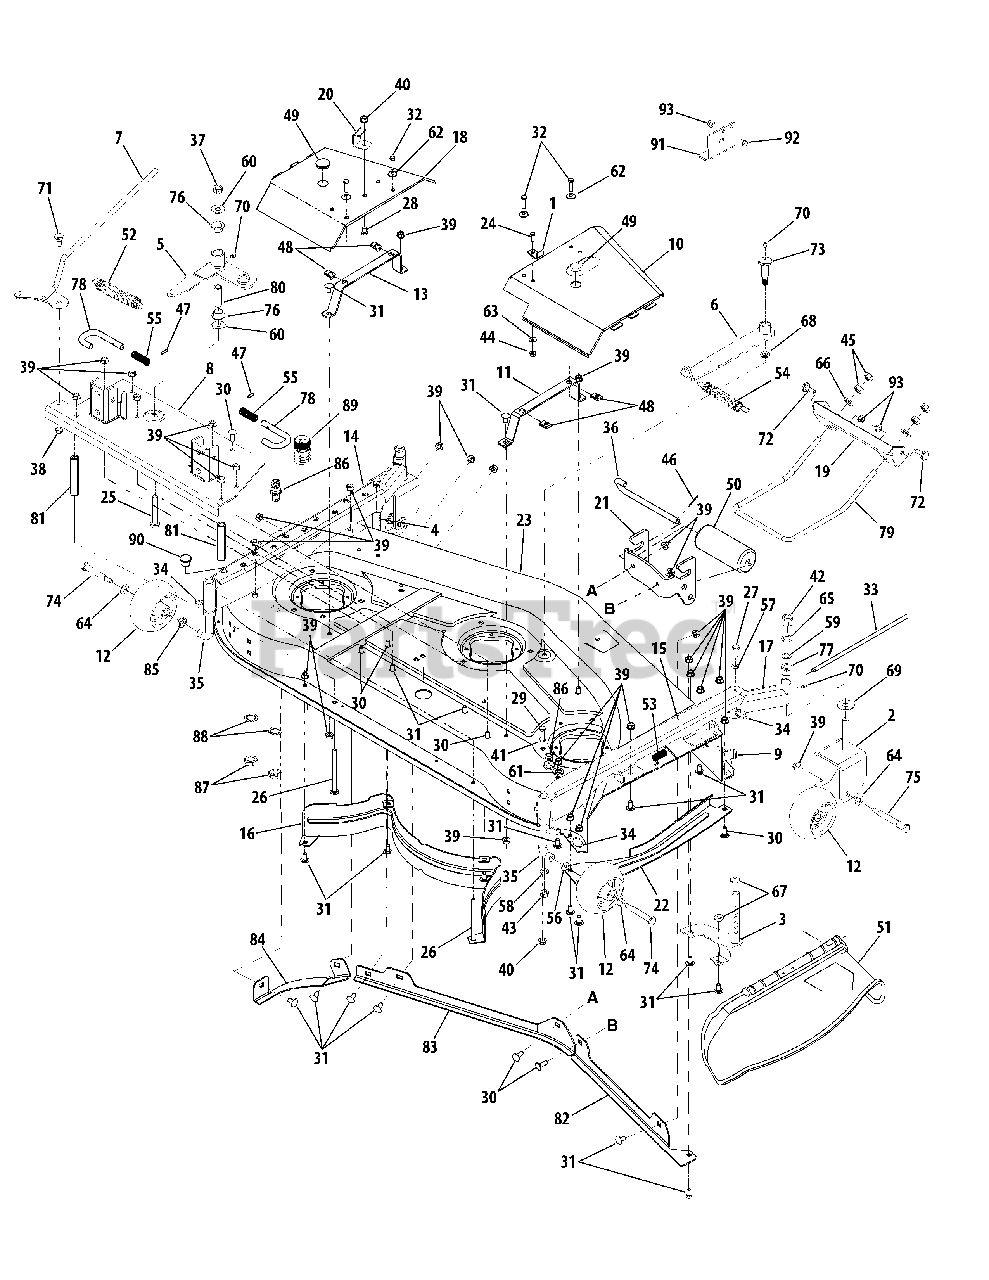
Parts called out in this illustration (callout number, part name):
1	Brackt, Hook Retainer
2	Bracket, Wheel
3	Spindle, Adjustment RH
4	Spindle, Adjustment LH
5	Bracket, Idler
6	Bracket, Idler
7	Handle
8	Bracket, Rear Hanger
9	Bracket, Chute Stop
10	Cover, Belt RH
11	Strap, Mounting
12	Wheel, Ball w/Fitting, 5 in
13	Strap, Mounting
14	Channel, Castor LH
15	Channel, Castor RH
16	Baffl e, Rear Inner
17	Castor, Front
18	Cover, Belt LH
19	Bracket, Front Lift
20	Bracket, Stop
21	Bracket, Roller Front
22	Guard, Finger
23	Deck Housing
24	Screw, Hex Cap 1/4-20 x .62 GR5
25	Screw, Hex Cap, 1/2-20 x 3.0 GR8
26	Carriage, Bolt 3/8-16 x 5.0 GR5
27	Screw, Hex Cap, 3/8-16 x .88 GR5
28	Screw, Hex Cap, 5/16-18 x .5 GR5
29	Screw, Hex Cap, 5/16-18 x 2.25 GR5
30	Carriage, Bolt 3/8-16 x 1.0
31	Carriage, Bolt 3/8-16 x .75
32	Screw, Hex Cap, 5/16-18 x 1 GR5
33	Pin, Hinge .3175 x 14.06
34	Pin, Clevis w/Ball Detent
35	Axle, Castor
36	Pin, Roller 1/2 x 7.31
37	Nut, Hex Lock, 1/2-20 GRA
38	Nut, Hex Lock, 3/8-16 GRA
39	Nut, Flange Lock 3/8-16
40	Nut, Flange Lock, 5/16-18 GR5
41	Nut, Hex , 5/16-18 GR5
42	Nut, Hex Lock 5/8-11
43	Nut, Hex, 7/16-14 GR2
44	Nut, Hex Flange Lock 1/4-20
45	Nut, Hex, 1/2-13
46	Pin, Cotter 3/32 x 1.25
47	Pin, Spirol
48	Nut, "U" 5/16-18
49	Plug, Button
50	Roller, Front
51	Deflector, Chute
52	Spring, Extension
53	Spring, Torsion
54	Spring, Extension
55	Spring, Compression
56	Washer, Bell, .375 x .87 x .063
57	Washer, Lock 3/8" I.D.
58	Washer, Lock 7/16" I.D.
59	Washer, Wave, .625 x .885 x .015
60	Washer, Flat, .5 x 1.25 x .10
61	Washer, Flat, .535 x .93 x .09
62	Washer, Bell .34" I.D.
63	Washer, Bell .265 x .75 x .062
64	Washer, Flat, .51 x 1.0 x .06
65	Washer, Flat, .625 x 1.0 x .067
66	Washer, Flat, .531 x 1.062 x .134 HT
67	Washer, Flat, .406 x .875 x .105
68	Washer, Flat, .469 x .875 x .105
69	Washer, Flat, 1.595 x .635 x .062 HT
70	Fitting, Lube, 3/16 Drive
71	Screw, Shoulder, .498 x .34: 3/8-16
72	Screw, Shoulder, .5 x .434: 3/8-16
73	Screw, Shoulder, .68 x 1.59
74	Screw, Shoulder, .5 x 2.5
75	Screw, Step Shoulder, 5/8-1/2 x 3.4
76	Bearing, Flange, 3/4 x .52
77	Bearing, Flange, .63 ID
78	Pin, Mower Support
79	Rod, Deck Hanger
80	Spacer, .5 x .75 x 2.07" Lg.
81	Spacer, .405" x .75 x 3.875" Lg.
82	Skirt, RH Deck
83	Skirt, LH Deck
84	Skirt, LH Extension
85	Spacer, Shoulder
86	Nozzle, Deck Wash
87	Nut, Hex, M16-1.5
88	Washer, Lock
89	Adapter, Water Nozzle
90	Plug, Screw, M16-1.5
91	Bracket, Up-Stop
92	Screw, Hex Cap, 3/8-16 x 1.0 Gr5
93	Nut, Flange Lock, 3/8-16 GrF
